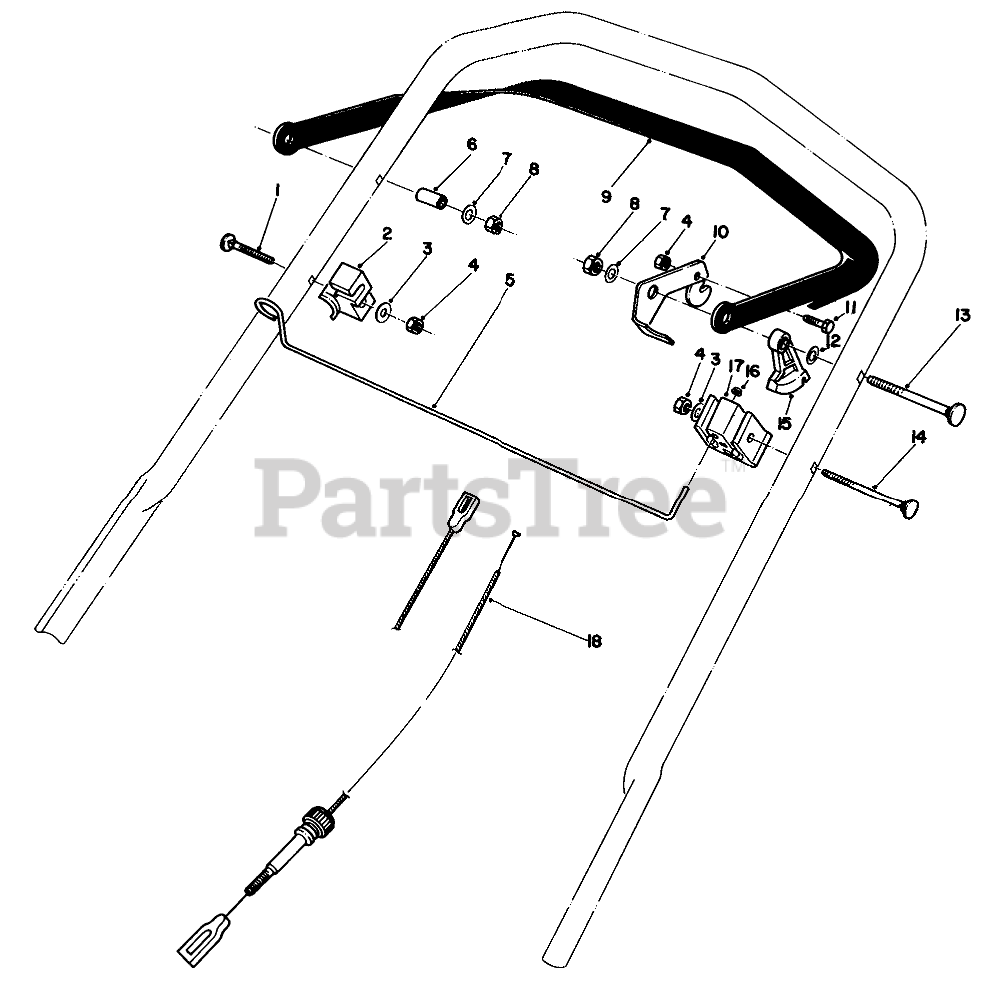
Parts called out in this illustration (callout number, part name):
1	SCREW-HANDLE
2	ROD CATCH
3	WASHER-FLAT
4	NUT-LOCK, NI
5	ROPE ROD PLATED
6	Spacer
7	WASHER-PLAIN
8	NUT-LOCK, NI
9	Bar-Control
10	Lever-Control
11	SCREW-HH
12	WASHER-FLAT
13	5/16-18 X 2 HNDLE SCREW
14	SCREW-HANDLE
15	LEVER-TRACTION
16	NUT-SPEED
17	SUPPORT-CABLE
18	CABLE-TRACTION
